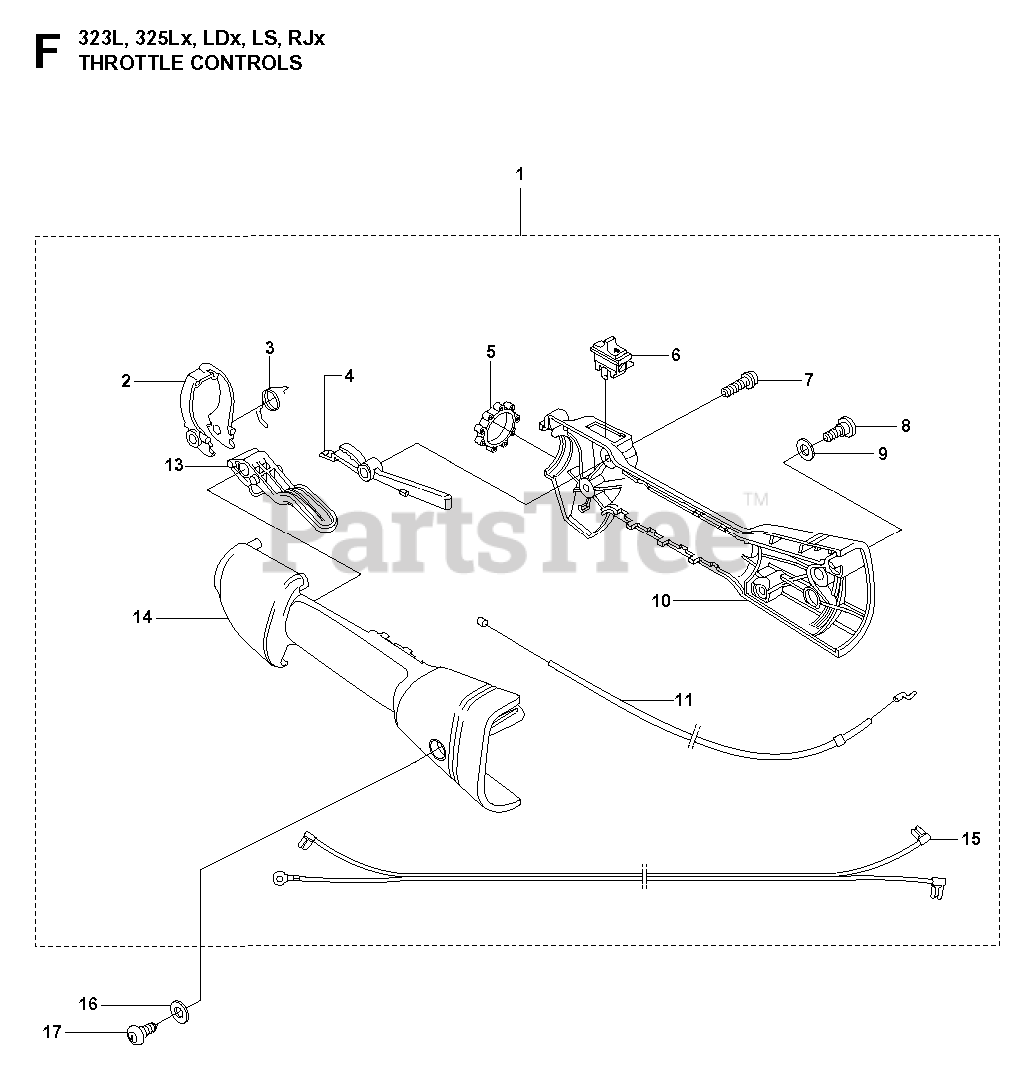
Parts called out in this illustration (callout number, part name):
4	THROTTLE LOCK
5	VIBRATION DAMPER
6	STOP BUTTON
8	SCREW MT5X11
9	O-RING 8X1.6
10	HSG THROTTLE RH
11	THROTTLE CABLE
13	THROTTLE TRIGGER
14	HANDLE HALF HSG LH
15	SHORT-CIRCUIT CABLE
16	O-RING 8X1.6
17	SCREW MT5X11
